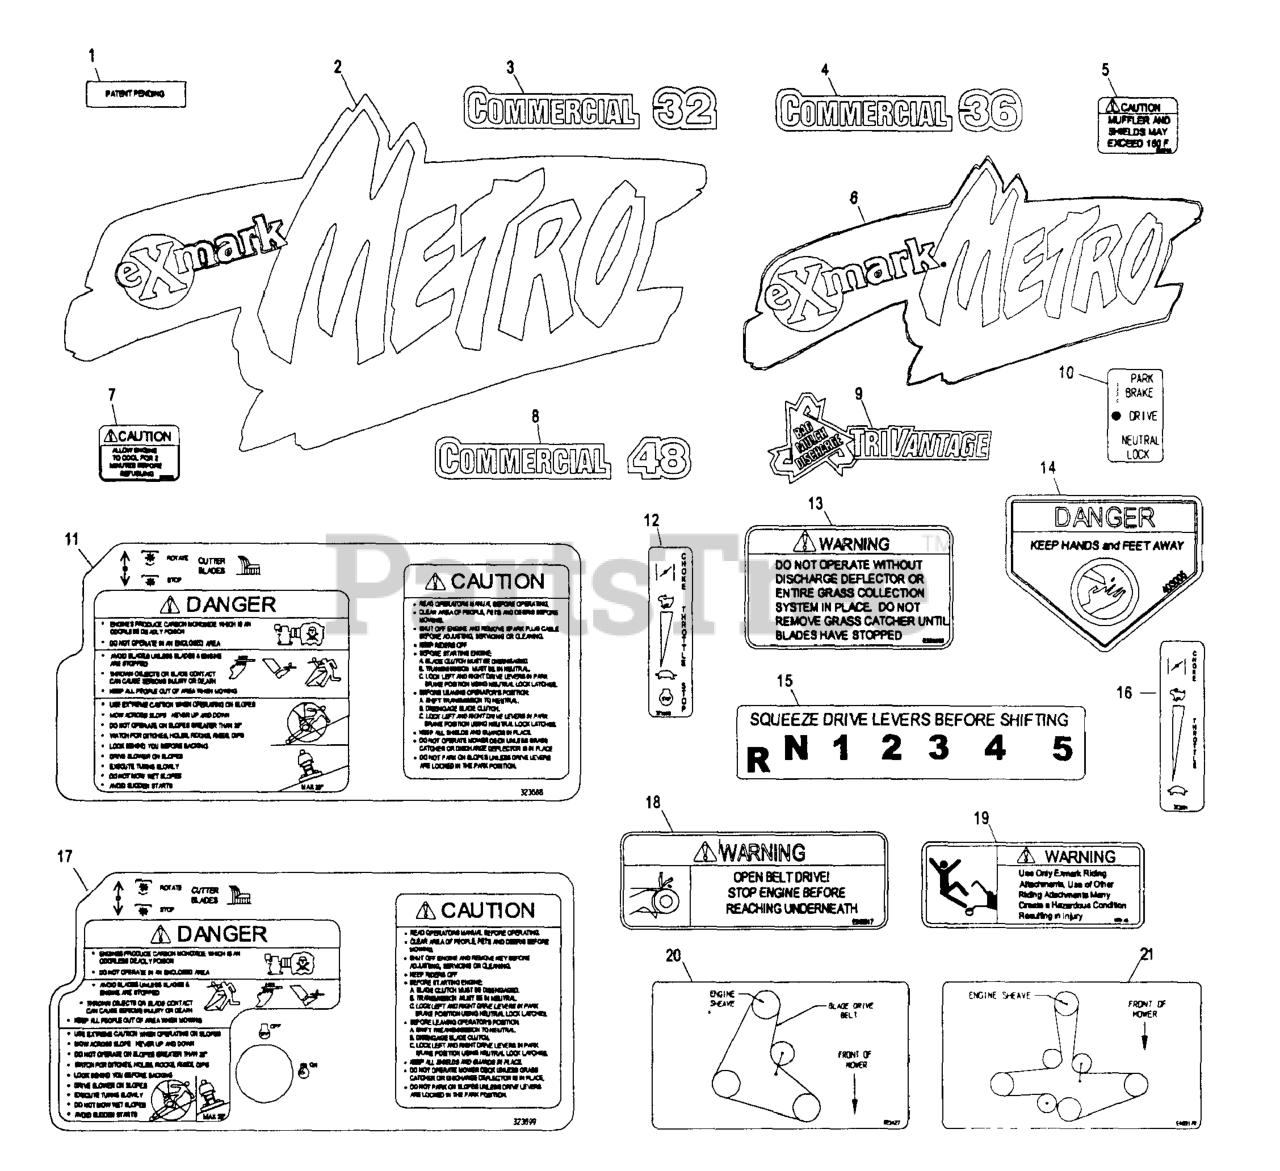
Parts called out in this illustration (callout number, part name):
1	Decal, Patent Pending
3	DECAL,COMMERCIAL 32
4	DECAL,COMMERCIAL 36
8	DECAL,COMMERCIAL 48
10	DECAL,NEUTRAL/BRAKE
13	DECAL-WARNING, DISCHARGE
14	DECAL-DANGER
15	DECAL,SHIFTER
16	DECAL,THROTTLE
18	DECAL,BELT DRIVE
19	DECAL,SULKY WARNING
20	DECAL,BELT ROUTING 32/36
